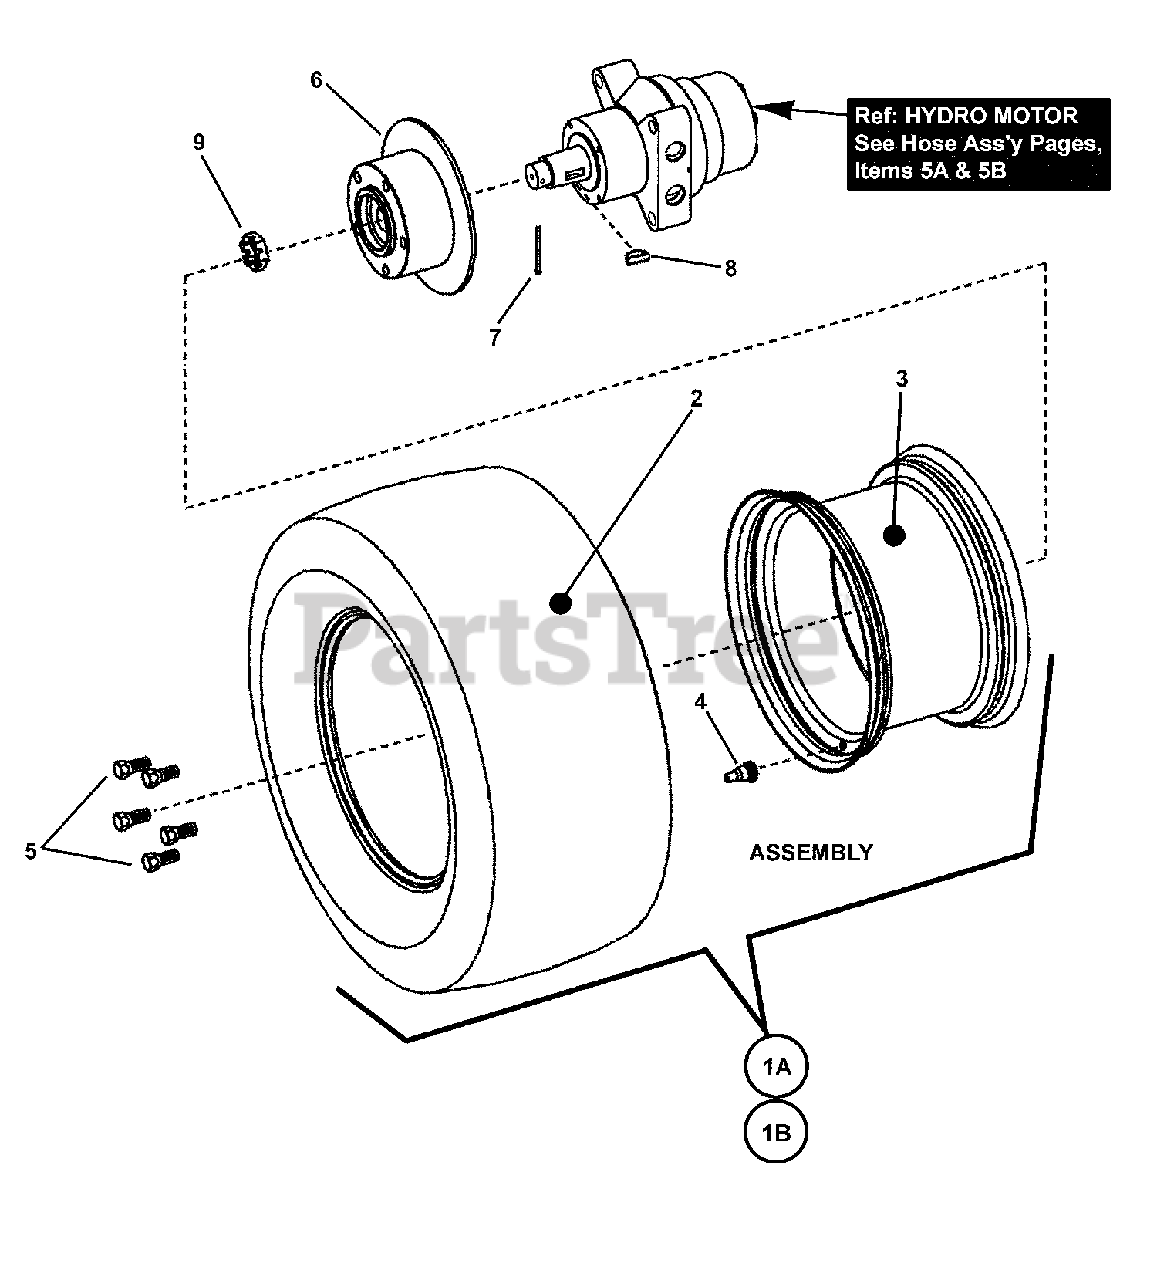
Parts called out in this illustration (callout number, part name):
1A	ASSEMBLY, 23" Rear Tire & Rim (Incl. Items 2, 3 & 4)
1B	ASSEMBLY, 24" Rear Tire & Rim (Incl. Items 2, 3 & 4)
2	TIRE, 24 x 12.00 - 12 HHS 49R (Carlisle)
3	RIM, 12" Diameter x 8.50"
4	VALVE, Air
5	NUT, 1/2-20NF Lug
6	DRUM, Brake (Ausco)
7	PIN, 9/64 x 1-1/2" Cotter
8	KEY, #11 Woodruff
9	NUT, 3/4-20 Slotted Hex
